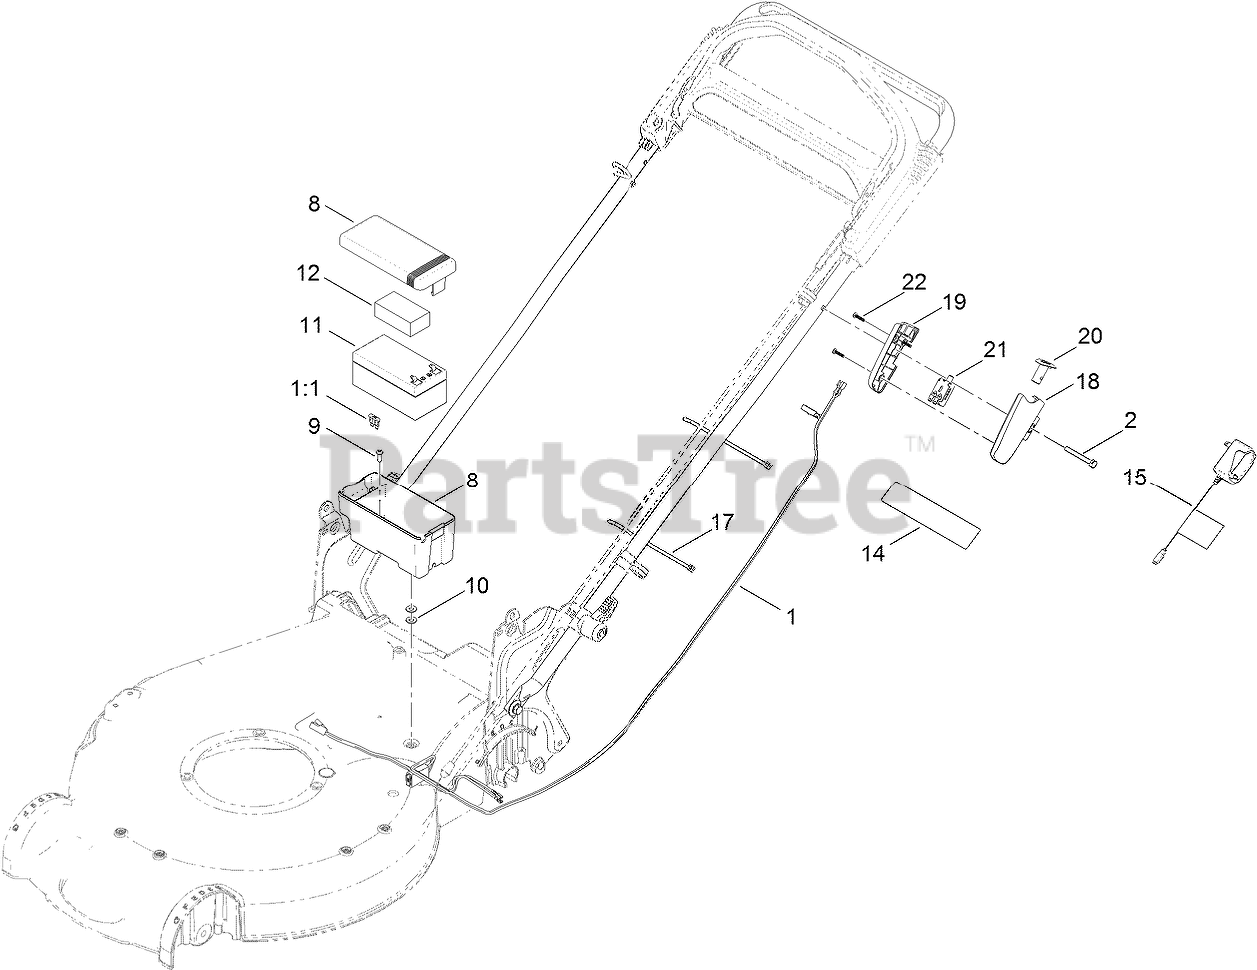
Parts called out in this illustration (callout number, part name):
1	HARNESS-WIRE
1:1	FUSE-40 AMP
2	SCREW-HH
8	BATTERY BOX ASM
10	WASHER-FLAT
11	BATTERY-WET
12	FOAM-BATTERY, TOP
14	DECAL-WARNING
15	CHARGER-BATTERY
17	TIE-CABLE
18	HOUSING-SWITCH, LH
19	HOUSING-SWITCH, RH
20	BUTTON-SWITCH
21	SWITCH-PUSH BUTTON
22	SCREW-PPH
